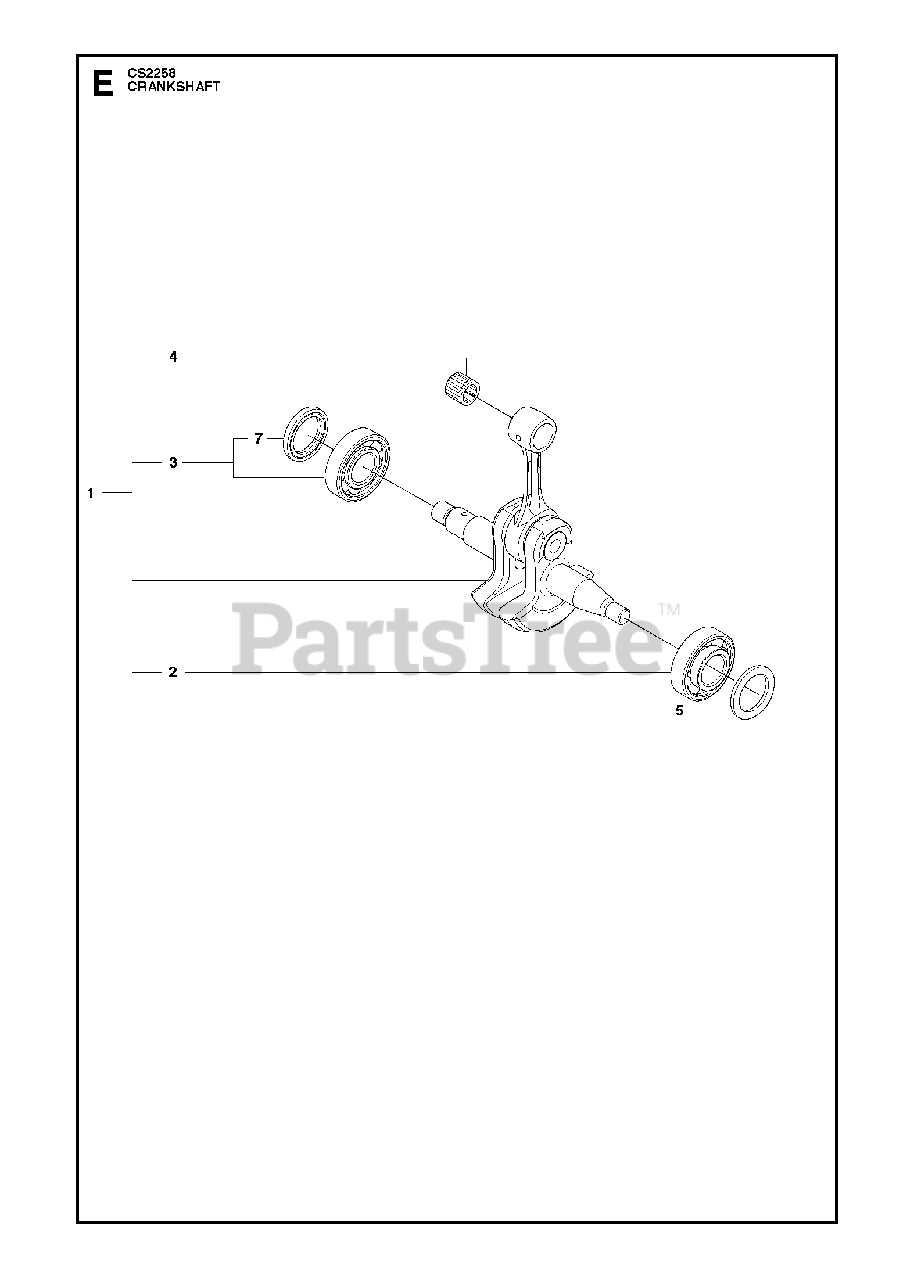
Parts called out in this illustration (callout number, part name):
1	CRANKSHAFT ASSY
2	BALL BEARING
3	BALL BEARING
4	NEEDLE BEARING
5	RADIAL SEAL
7	SEALING
